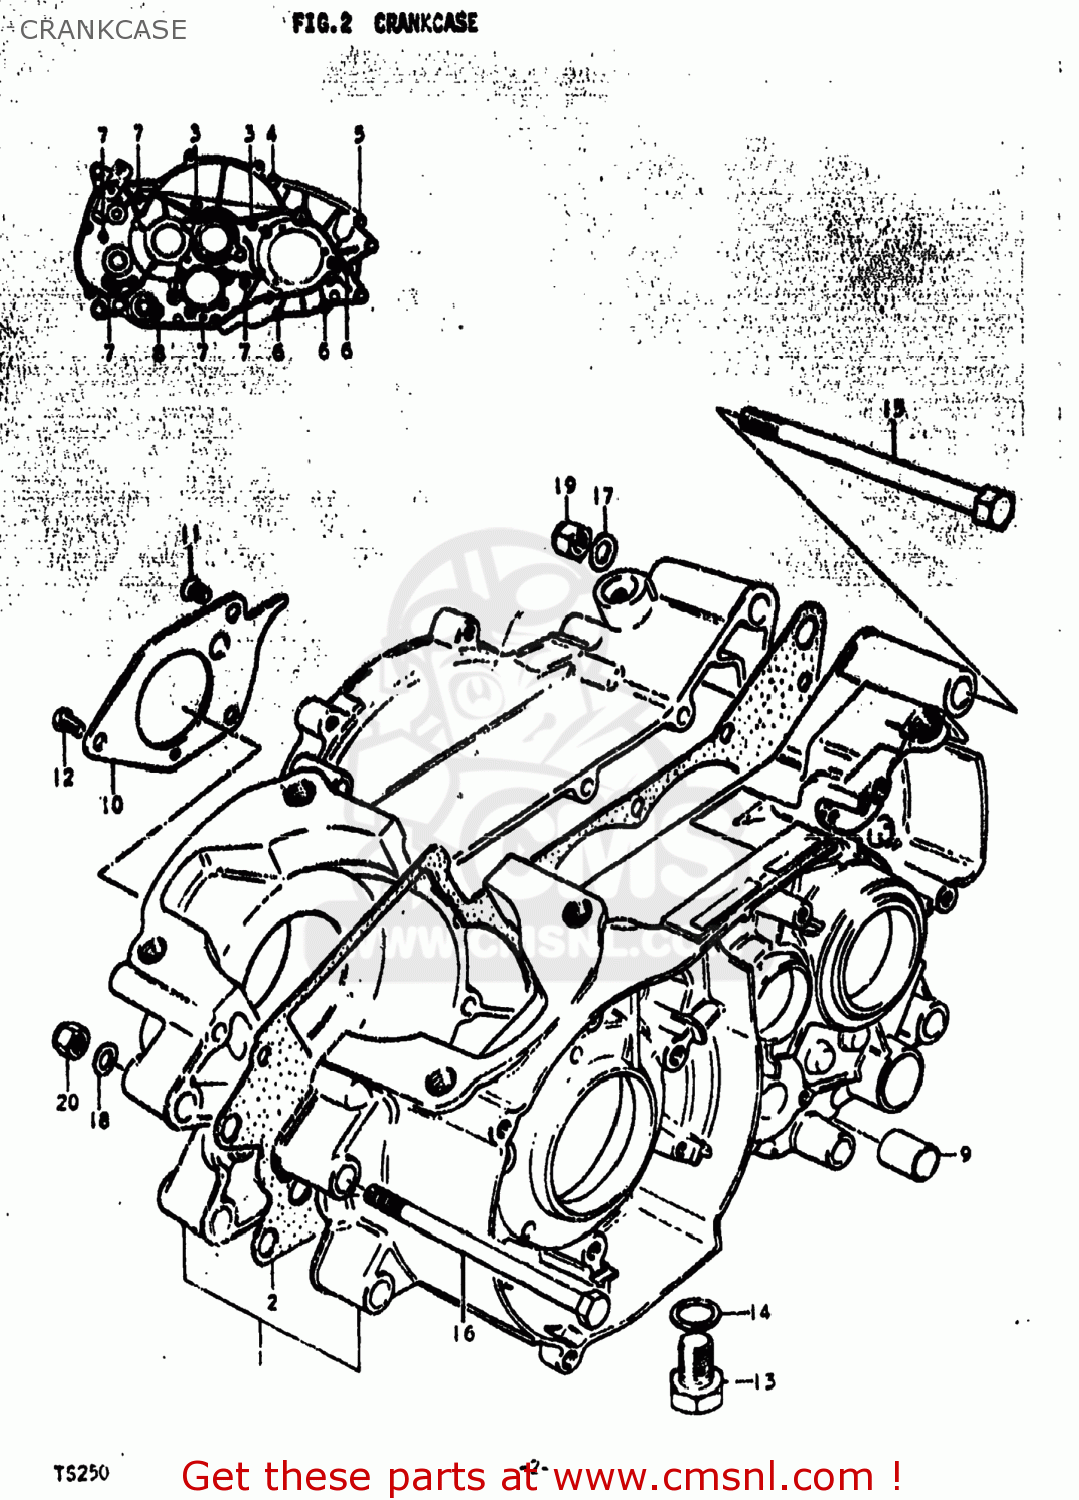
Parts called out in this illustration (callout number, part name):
1	CRANKCASE SET
2	GASKET,CRANKCASE (MCA)
3	SCREW
4	SCREW 6X70
5	SCREW
6	SCREW
7	SCREW (6X45)
8	SCREW (6X35)
9	PIN
10	PLATE,OIL RESERVOIR
11	SCREW
12	SCREW
13	PLUG
14	GASKET(14X19.2X2) (NAS)
15	BOLT 10X120
16	HEXAGON BOLT 8X80
17	WASHER
18	WASHER
19	NUT
20	NUT
